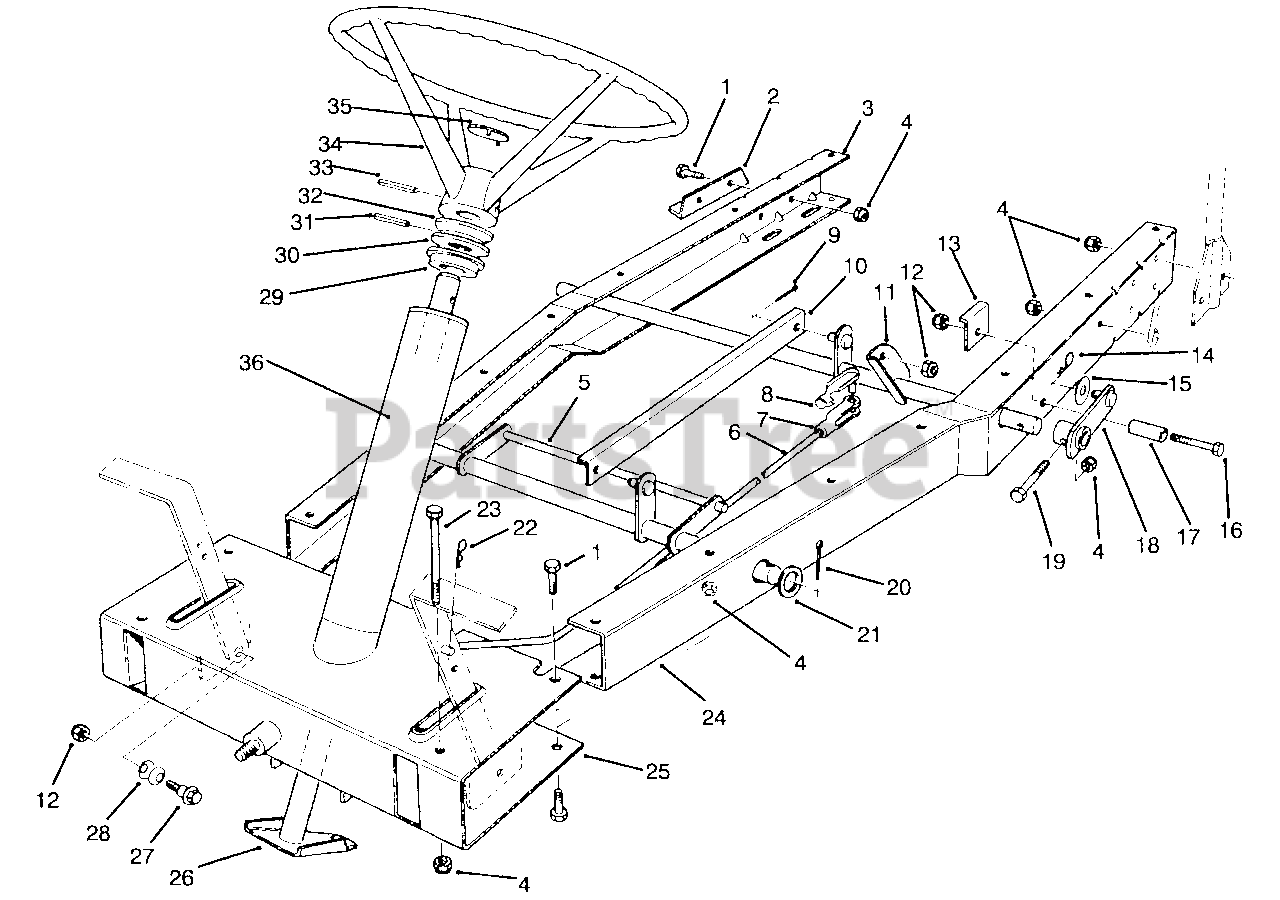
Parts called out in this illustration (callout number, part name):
1	Screw-Cap Hex. Hd.
2	Mount-Bearing, Axle
3	Channel-R.H.
4	Nut-Lock
5	Lift W.A.-Front, Deck
6	Rod-Clutch
8	Assembly-Pin, Clevis
9	Pin-Cotter
10	Bracket-Link, H.O.C.
11	Tube W.A.-Support, Rear
12	Nut-Lock
13	Brace-Stop, Deck
14	Pin-Hair, Cotter
15	Washer-Flat
16	Screw-Cap Hex. Hd.
17	Spacer-Stop, Deck
18	Lever W.A.-H.O.C.
19	Bolt-Mounting, Axle
20	Pin-Cotter
21	Washer-Flat
22	Pin-Hair, Cotter
23	Screw-Cap Hex. Hd.
24	Channel-L.H.
25	Frame W.A.-Front
26	Shaft W.A.-Steering
27	Bolt-Shoulder
28	Washer-Belleville
29	Bushing-Steering
30	Washer-Steering
32	Spacer-Steering
34	Wheel-Steering
35	Insert-Wheel, Steering
